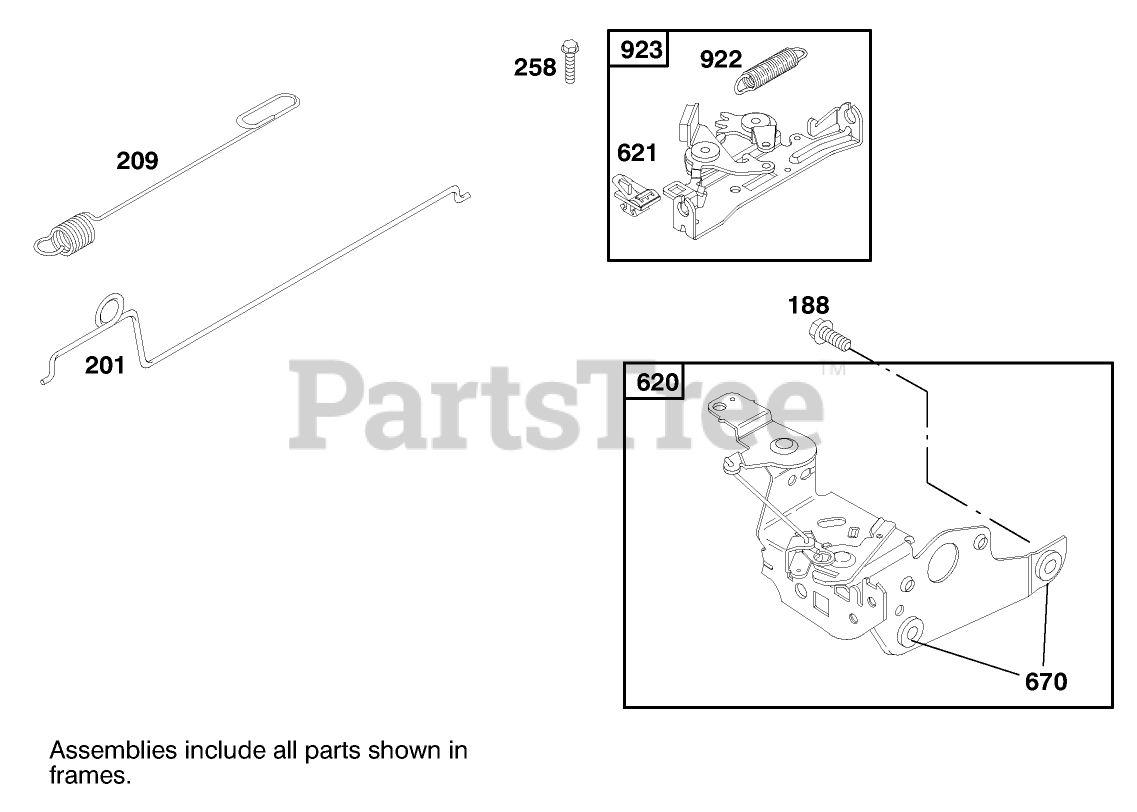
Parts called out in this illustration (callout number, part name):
188	Screw-Hex.
201	Link-Govemor
209	Governor Spring
258	Screw-Sem
620	Bracket-Control
621	Switch
670	Spacer
922	Brake Spring
923	Brake
